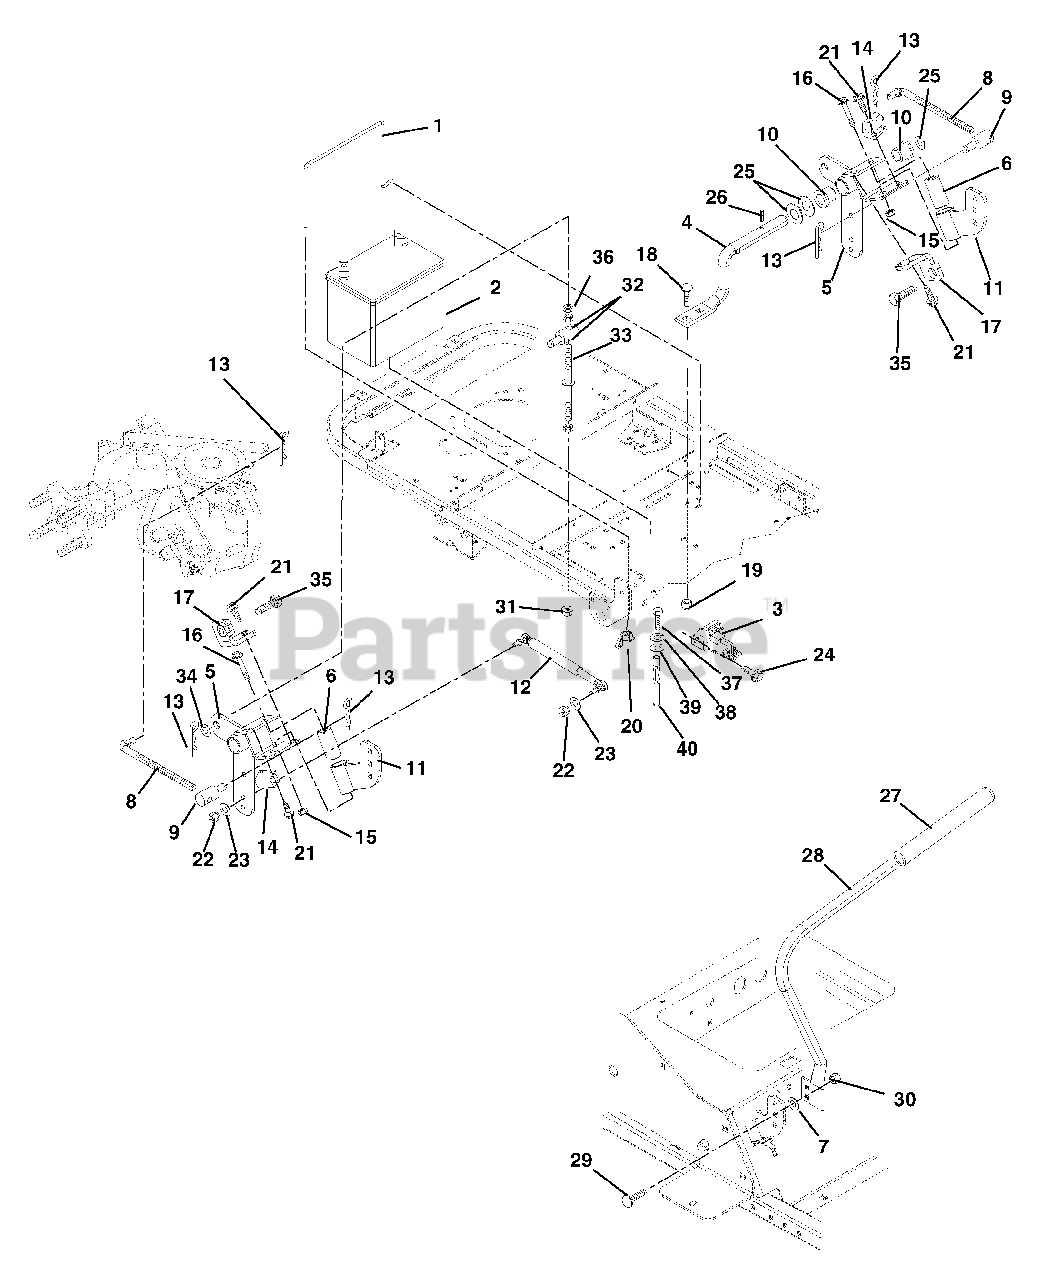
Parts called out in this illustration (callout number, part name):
1	Battery Rod
2	Battery (12 Volt, 330 CCA, 50 Min. Reserve Cap.) (043)
3	Solenoid
4	Rod Pivot
5	Weldment, Control
7	Washer, Locking Extenal .326 x .599 x .031
8	Link, Wireform
9	Pivot, Rod
10	Bushing 1.00 x .75 x 1.00
11	Weldment, Handlebar
13	Pin, Hair
14	Switch, Double Pole N.O./N.O.
15	Nut, Locking Top Flange .50-13
16	Bolt, Hex .50-13 x 3.00 Grade 5
17	Bracket, Tracking
18	Bolt, Round Head Square Neck .38-16 x 1.00 Grade 5
19	Nut .38-16 Flange Nyloc
20	Nut, Locking Wing .25-20
21	Screw, Tapping 10-24 x .50 Hex Washer Head
22	Nut, Hex M8-1.25
23	Washer, Locking .31 x .078 Regular
24	Screw, Tapping .25-20 x .37 Hex Washer Head
25	Washer, Flat Steel .754 x 1.00 x .032
26	Pin, Roll .188 x 1.13
27	Grip, Handlebar
28	Handlebar, Right Hand
28	Handlebar, Left Hand
29	Bolt, Round Head Square Neck .31-18 x .88 Grade 5
30	Nut, .31-18 Flange Nyloc
31	Nut, .38-16 Flange Nyloc
32	Nut, Hex .38-16
33	Rod, Tracking
34	Nut, Locking Jam Patch 1.00-20
35	Screw, Socket Head .25-20 x 1.25
36	Trunnion
37	Bolt, Hex .31-18 x 1.00 Grade 5
38	Washer-Locking .31 x .078 Regular
39	Washer-Flat-Steel .344 x .688 x .065
